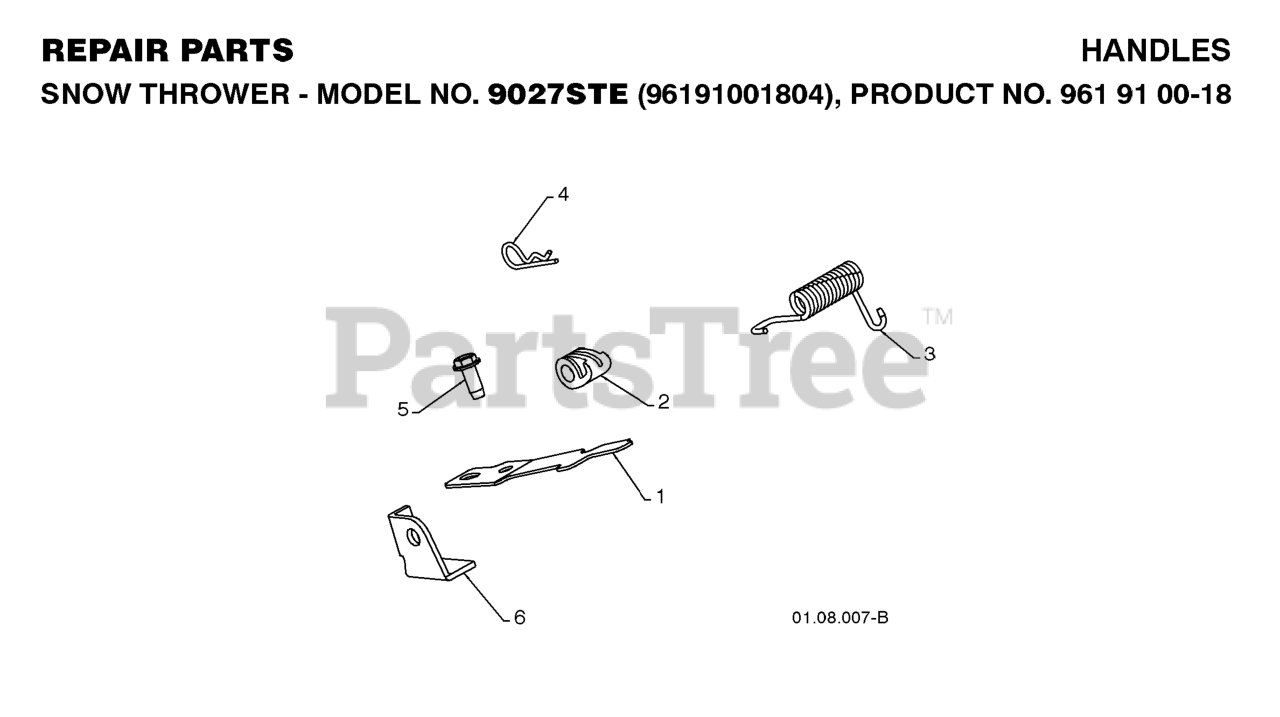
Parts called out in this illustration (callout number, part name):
1	SPRING.INTERLOCK
2	CAM.INTERLOCK.RELEASE
3	RP SPRING, TORSION
4	SPRING RETAINER
5	SCREW 14-20 X 5/8
6	STOP.INTERTLOCK
